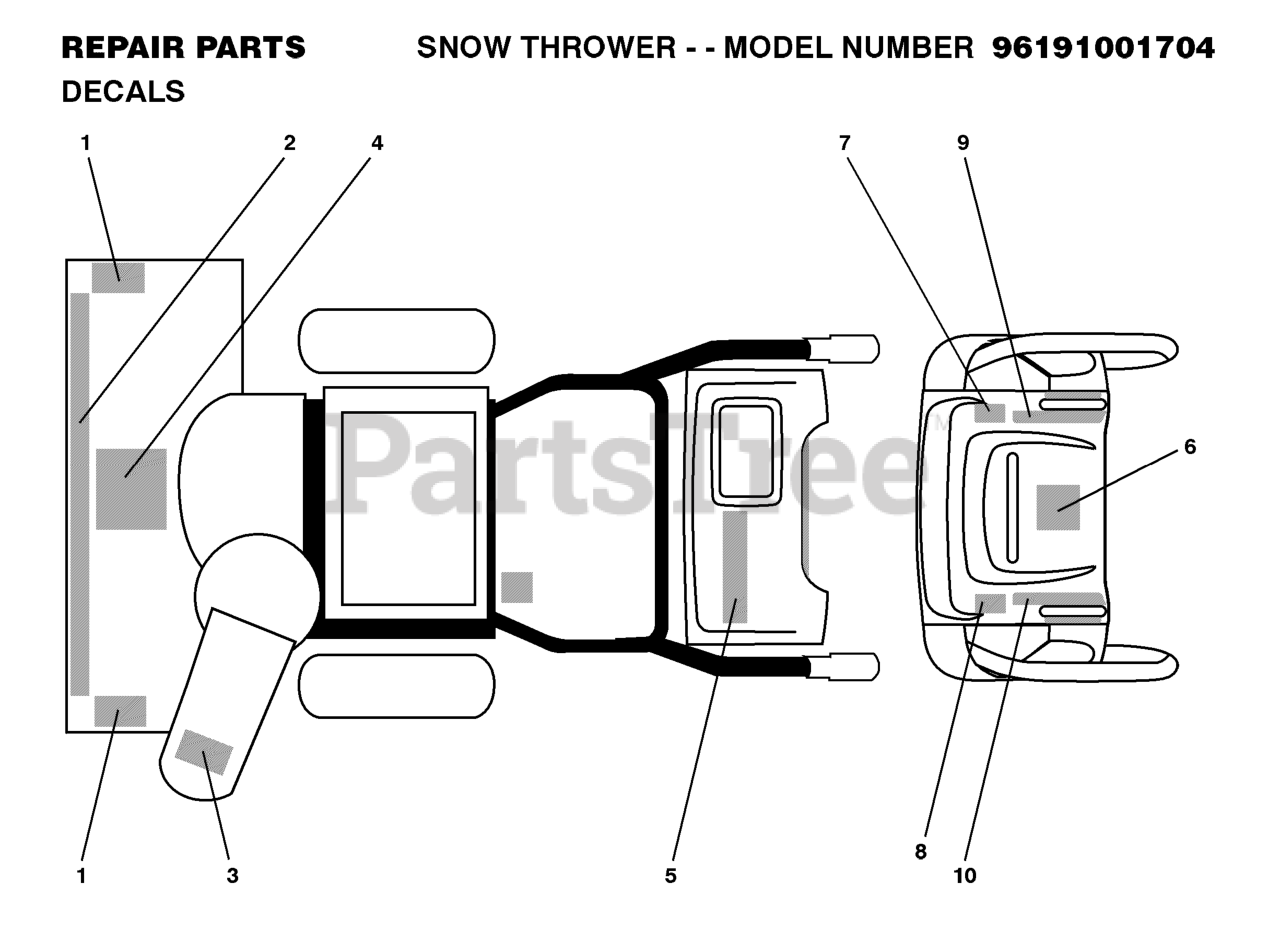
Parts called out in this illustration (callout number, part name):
1	DECAL.AUGER.SAFETY.
3	DECAL.CHUTE.SAFETY.
4	DECAL.AUGER."
6	DECAL.CONSOLE.INSTRUCTION
10	DECAL.REM.DEFLECTOR.LT
11	DECAL.BELT.GUARD.
12	DECAL.FENDER
